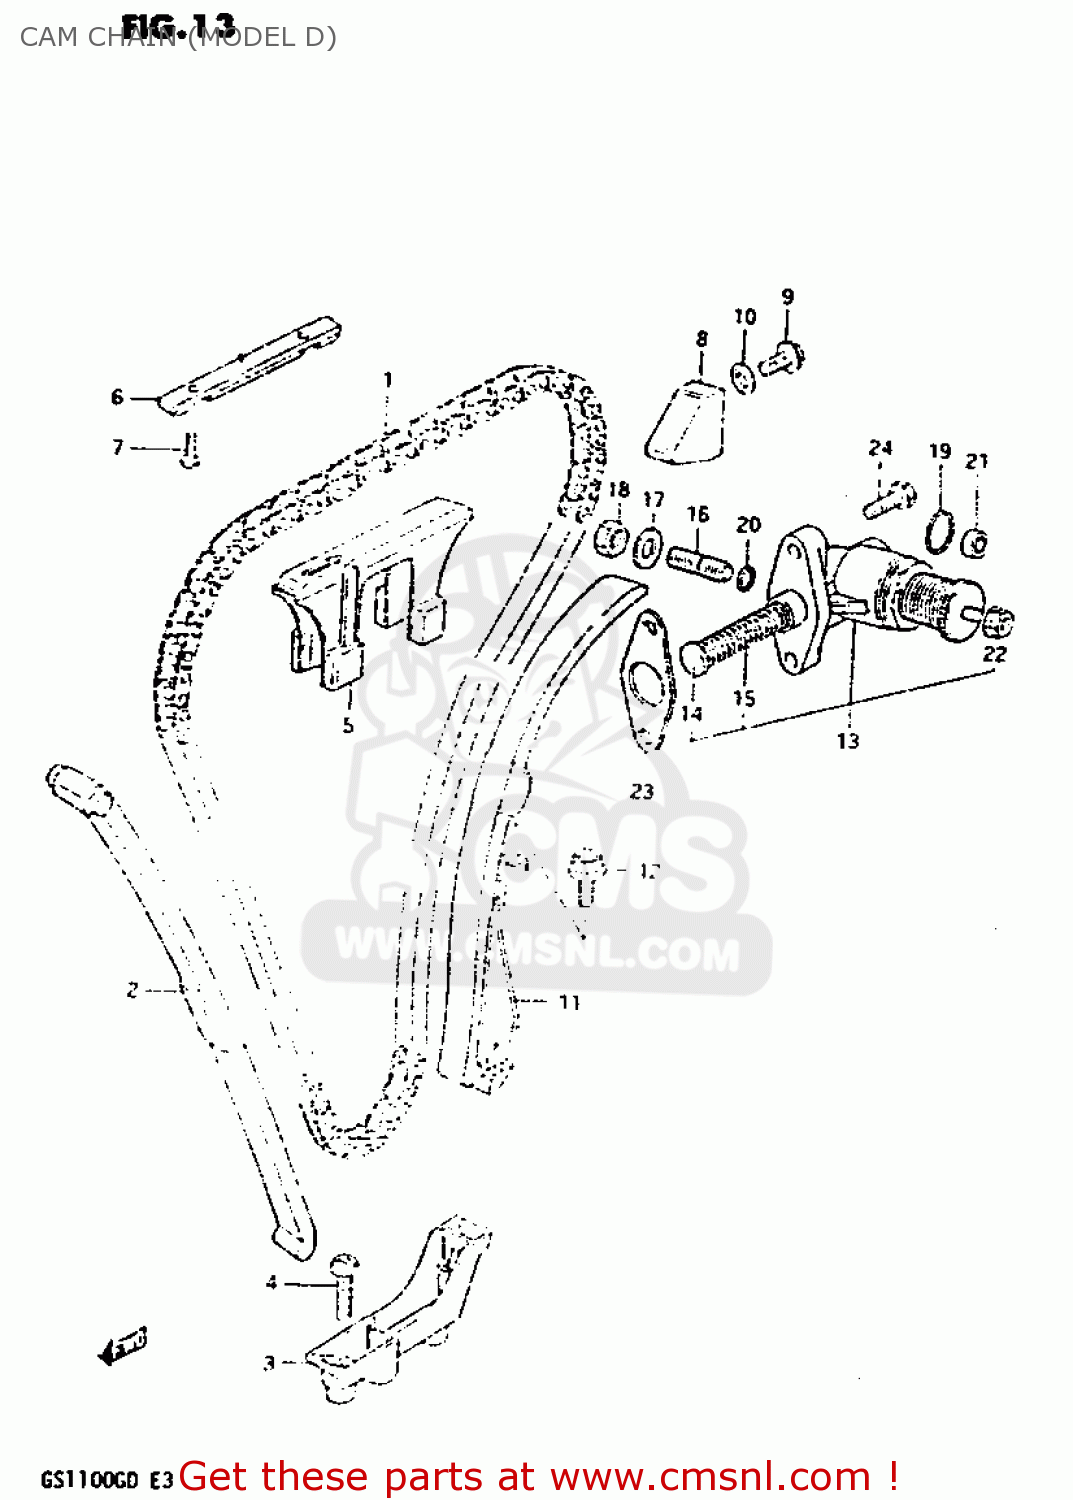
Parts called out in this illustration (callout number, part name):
1	CHAIN,CAMSHAFT DRIVE
2	GUIDE,CAM CHAIN NO.1
3	HOLDER,CAM CHAIN GUIDE
4	SCREW
5	GUIDE,CAM CHAIN NO.2
6	GUIDE,CAM CHAIN
7	SCREW
8	GUIDE,CAM CHAIN
9	BOLT 6X12
10	GASKET(5.8X13X1.2) (NAS)
11	TENSIONER,CAM CHAIN
12	BOLT 8X16
13	ADJUSTER ASSEMBLY,TENSIONER
14	ROD,PUSH
15	SPRING
16	SCREW,TENSIONER ADJUST
17	WASHER
18	NUT
19	O RING(D:2.4,ID:20.8)
20	O RING(D:1.9,ID:5.7)
21	SEAL,OIL(10X16X4)
22	NUT 6MM
23	GASKET,TENSIONER ADJUSTER (MCA)
24	SCREW
